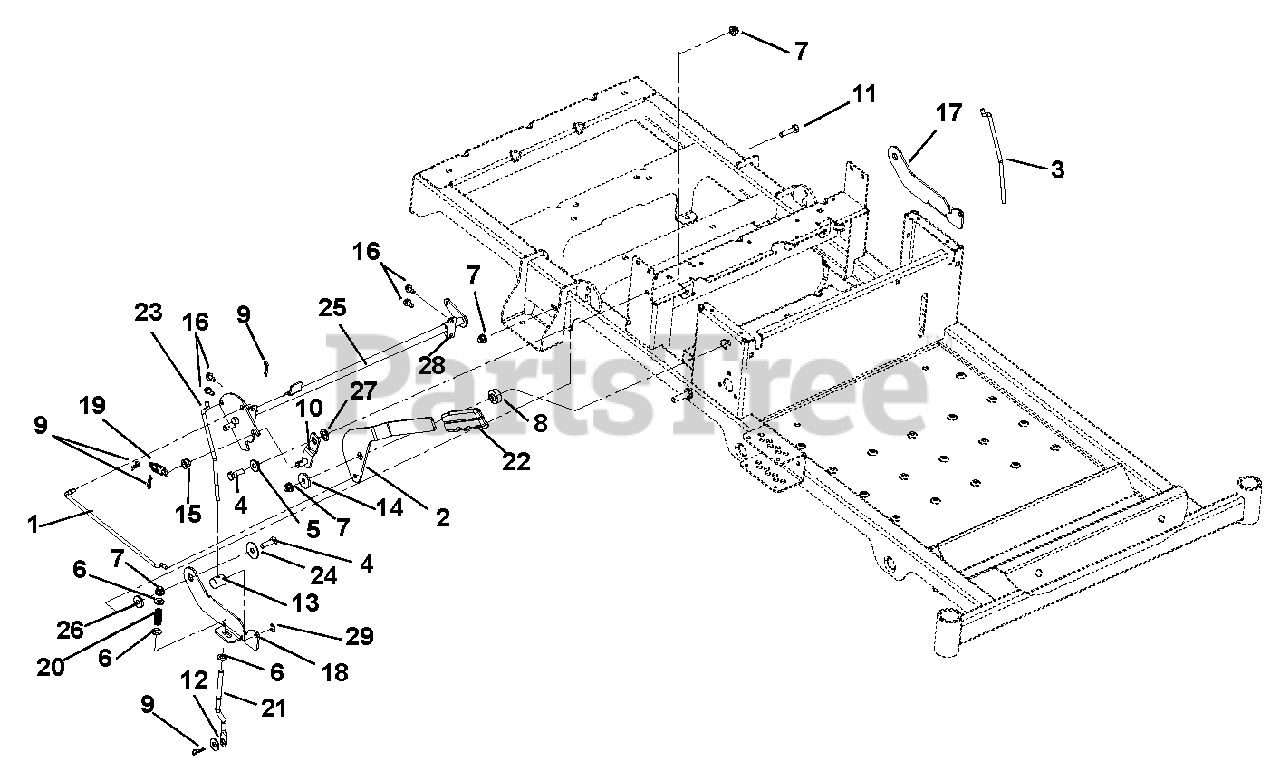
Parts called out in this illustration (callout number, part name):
1	Link, Brake Handle
2	Handle, Parking Brake
3	Link, Neutral LH
4	Bolt, Hex .31-18 x 1.00
5	Bushing, Flange .312 x .500 x .344 x .880
6	Washer, Flat, Steel .344 x .688 x .065
7	Nut, Flange Nyloc 5/16-18
8	Spacer, Brake Handle
9	Pin, Hair Internal .08 x .18 x 1.18
10	Weldment, Detent Arm
11	Bolt, Hex .31-18 x 1.25
12	Washer, Flat Steel .38 x .875 x .083
13	Trunnion, 1/4-20
14	Washer, Flat Steel .344 x 1.125 x .135
16	Screw, Tapping .25-20 x .50 Hex Washer Head
17	Latch, LH Neutral
18	Latch, RH Neutral
19	Spring, Tension .072 x .565 x 1.87
20	Spring, Compression
21	Link, Brake Cog
22	Grip, Parking Brake
23	Link, Neutral RH
24	Washer, Flat Steel .347 x 1.254 x .048
25	Weldment, Brake Shaft
26	Bushing, Flange .325 x .499 x .26 x .88
27	Washer, Flat, Steel .52 x .827 x .062
28	Bushing, .50 Clamp Block Molded
29	Ring, Retaining, External .250 x .025
